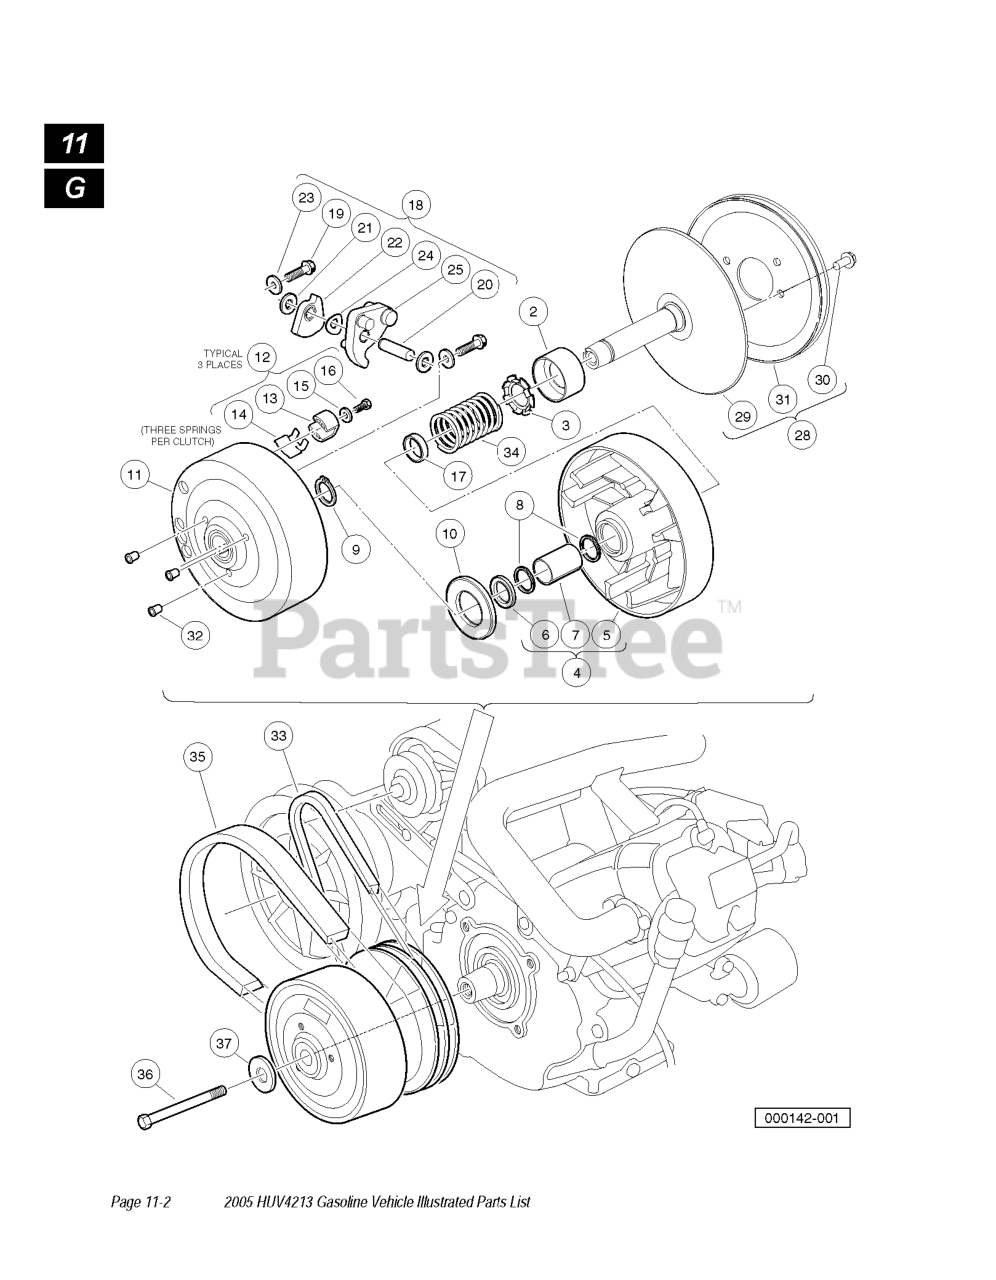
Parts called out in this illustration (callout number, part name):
1	DRIVE CLUTCH ASSY. FE 400
2	BEARING IDLER
3	RETAINER, SPRING
4	MOVABLE FACE ASSEMBLY
8	RING, SPIRAL BACKUP
9	RING .810" INTERNAL
10	WASHER, THRUST
11	DRIVE HUB ASSY
12	DRIVE CLUTCH BUTTON KIT
13	DRIVER, DRIVE CLUTCH
14	SPRING, DRIVE BUTTON
15	WASHER FLAT
16	SCREW, # 10-24 X .50 HEX
17	SPACER, FIXED FACE SHAFT
18	DRIVE CLUTCH WEIGHT KIT DS OHV
19	SCREW, 1/4-20 X 1.00 HEX HEAD
24	WASHER, WAVE
26	FIXED FACE DRIVE
33	BELT, STARTER-GENERATOR
34	SPRING DRIVE CLUTCH FE400
35	DRIVE BELT
36	SCREW 3/8-24X5.5 HEX LOC PTCH
37	WASHER, 3/8 TYPE B FLAT
